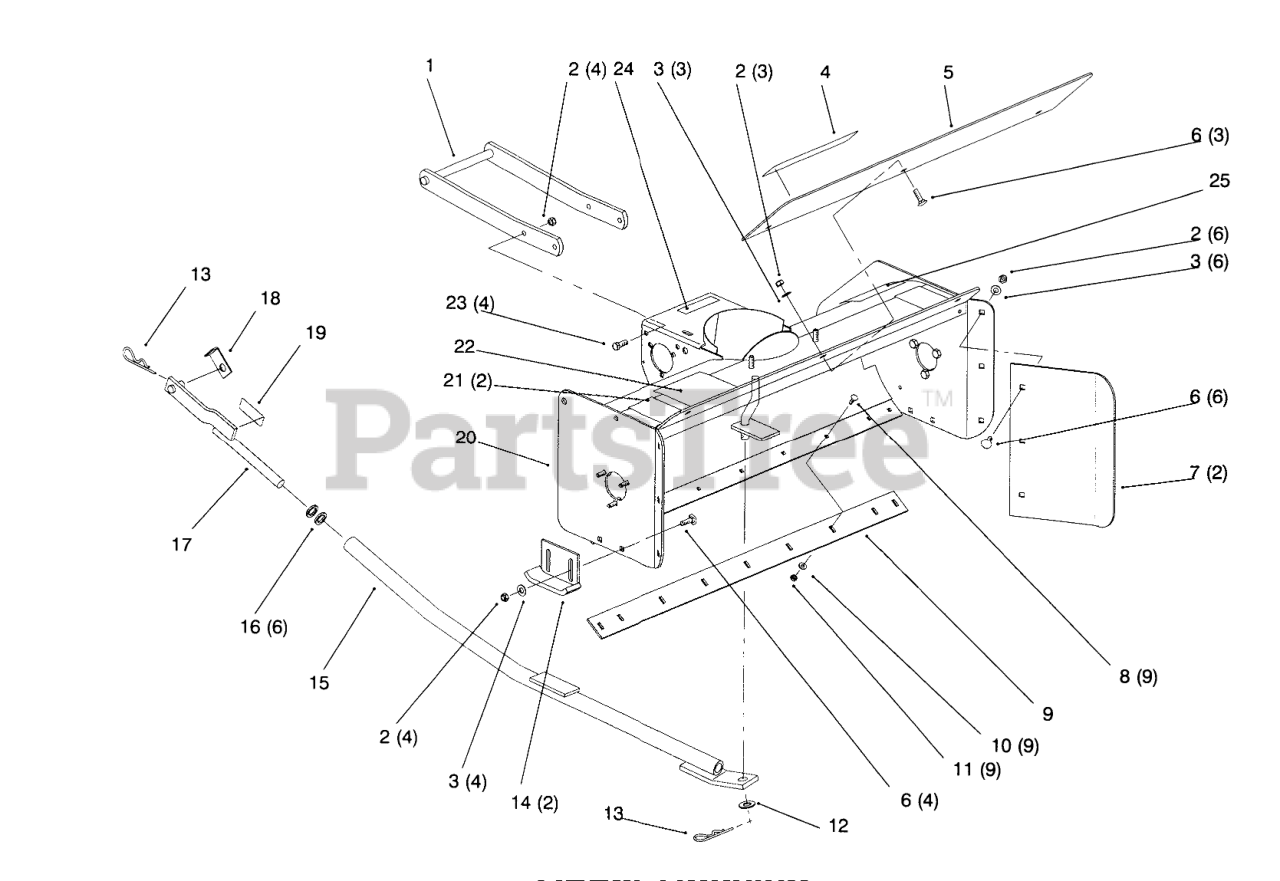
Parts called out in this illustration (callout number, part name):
2	NUT-LOCK, NI
3	WASHER-FLAT
4	DECAL-ATTACHMENT
5	PLATE-EXTENSION
6	BOLT-CARR
7	PLATE-EXTENSION, RH
8	SCREW-CARR
9	SCRAPER-REVERSIBLE
10	WASHER-FLAT
11	NUT-LOCK, NI
12	WASHER-FLAT
13	PIN-COTTER, HAIR
15	LIFT ROD
16	Washer
17	WLDMT-LIFT ROD BLK
17	CROSS REFERENCE TO 92-9778
18	RETAINER CLIP
19	DECAL - WARNING
20	Auger Housing ASM (Incl. Ref. 21, 22, 25)
21	DECAL-DANGER
22	DECAL-WARNING
23	SCREW-HH
25	DECAL - WARNING
